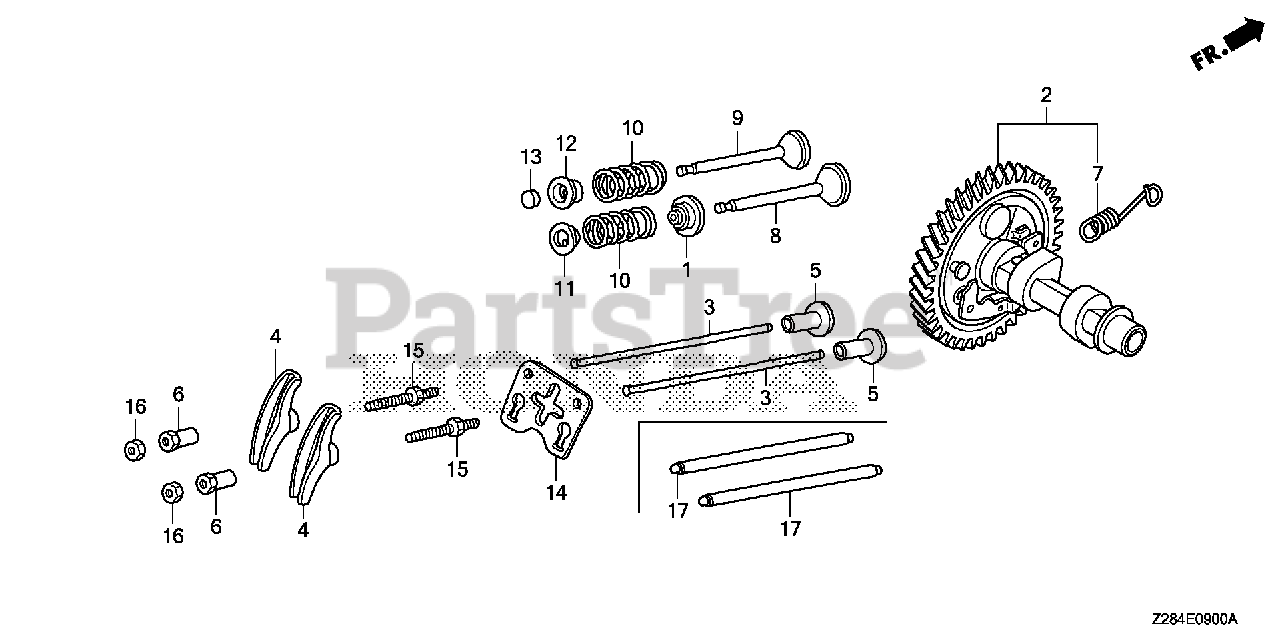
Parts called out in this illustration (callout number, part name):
1	SEAL, VALVE STEM
2	CAMSHAFT ASSY.
4	ARM, VALVE ROCKER
5	LIFTER, VALVE
6	PIVOT, ROCKER ARM
7	SPRING, WEIGHT RETURN
8	VALVE, IN.
9	VALVE, EX.
10	SPRING, VALVE
11	RETAINER, IN. VALVE SPRING
11	RETAINER, VALVE SPRING
12	RETAINER, IN. VALVE SPRING (EXHAUST SIDE)
12	RETAINER, VALVE SPRING
14	PLATE, PUSH ROD GUIDE
15	BOLT, PIVOT (8MM)
16	NUT, PIVOT ADJUSTING
